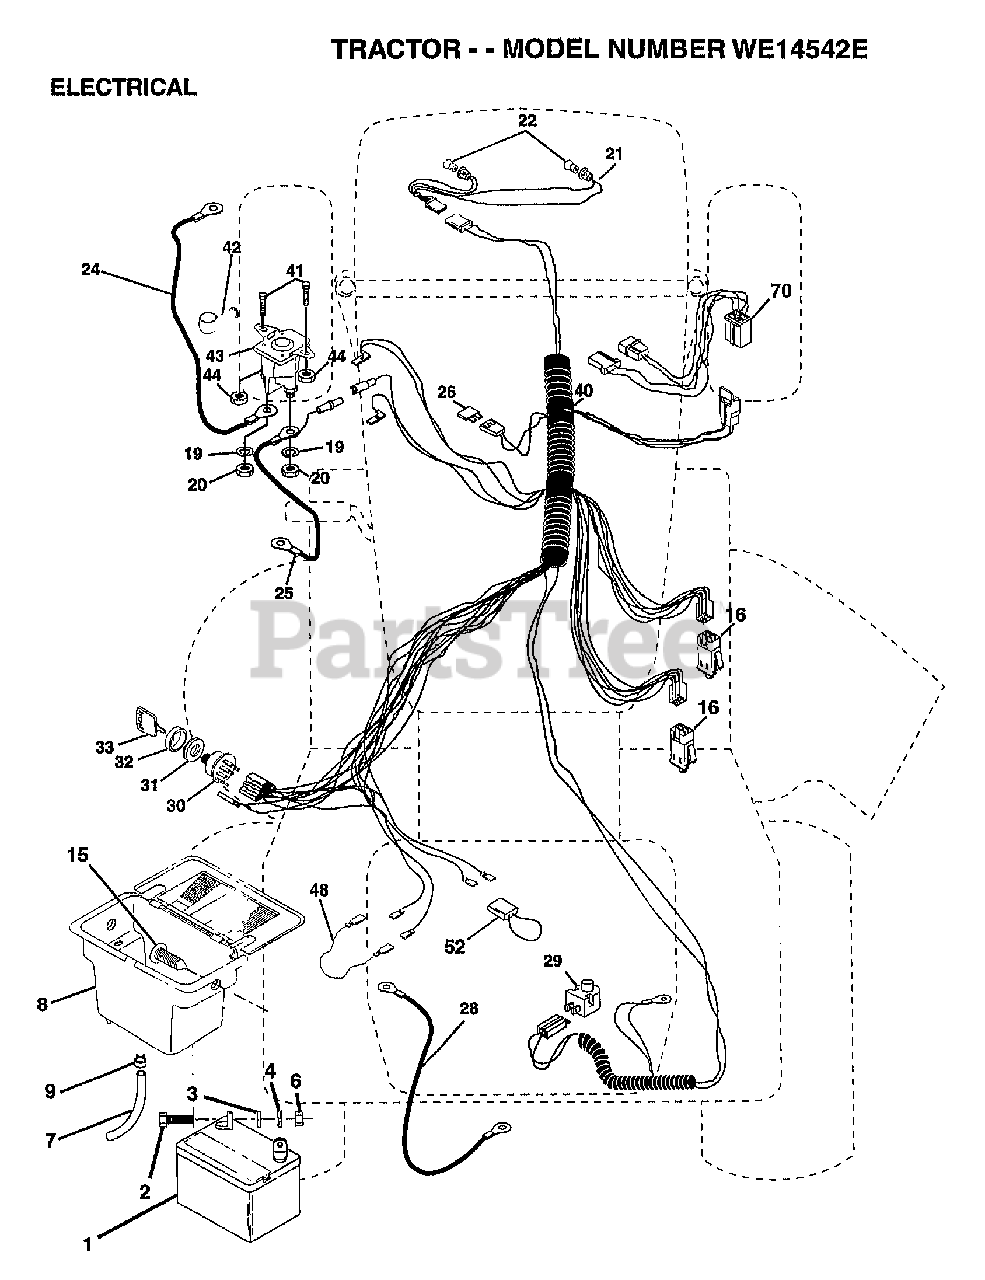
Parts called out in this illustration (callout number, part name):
2	BOLT LT
3	WASHER
4	LOCKWASHER
7	TUBE T
8	"CASE,BATTERY.MECH"
9	HOSE CLAMP T
15	FASTNER.SNAP-IN
16	SWITCH INTERLOCK
20	NUT
21	"HARNESS,LIGHT SOC"
22	HEADLAMP BULB
24	"CABLE T, BATTERY"
25	CABLE.BTRY.6GA.RD
26	FUSE HYT
28	CABLE T
29	SWITCH SEAT
30	SWITCH IGN 4POS
31	NUT IGNITION
32	COVER KEY SWITCH
33	KEY
40	HARNESS-IGNITION
41	BOLT HXHD FIN
44	NUT HXKEP 1/4X20
48	ADAPTER AMMETER
52	PROTECTION LOOP
70	HARNESS.ENG.DUAL
